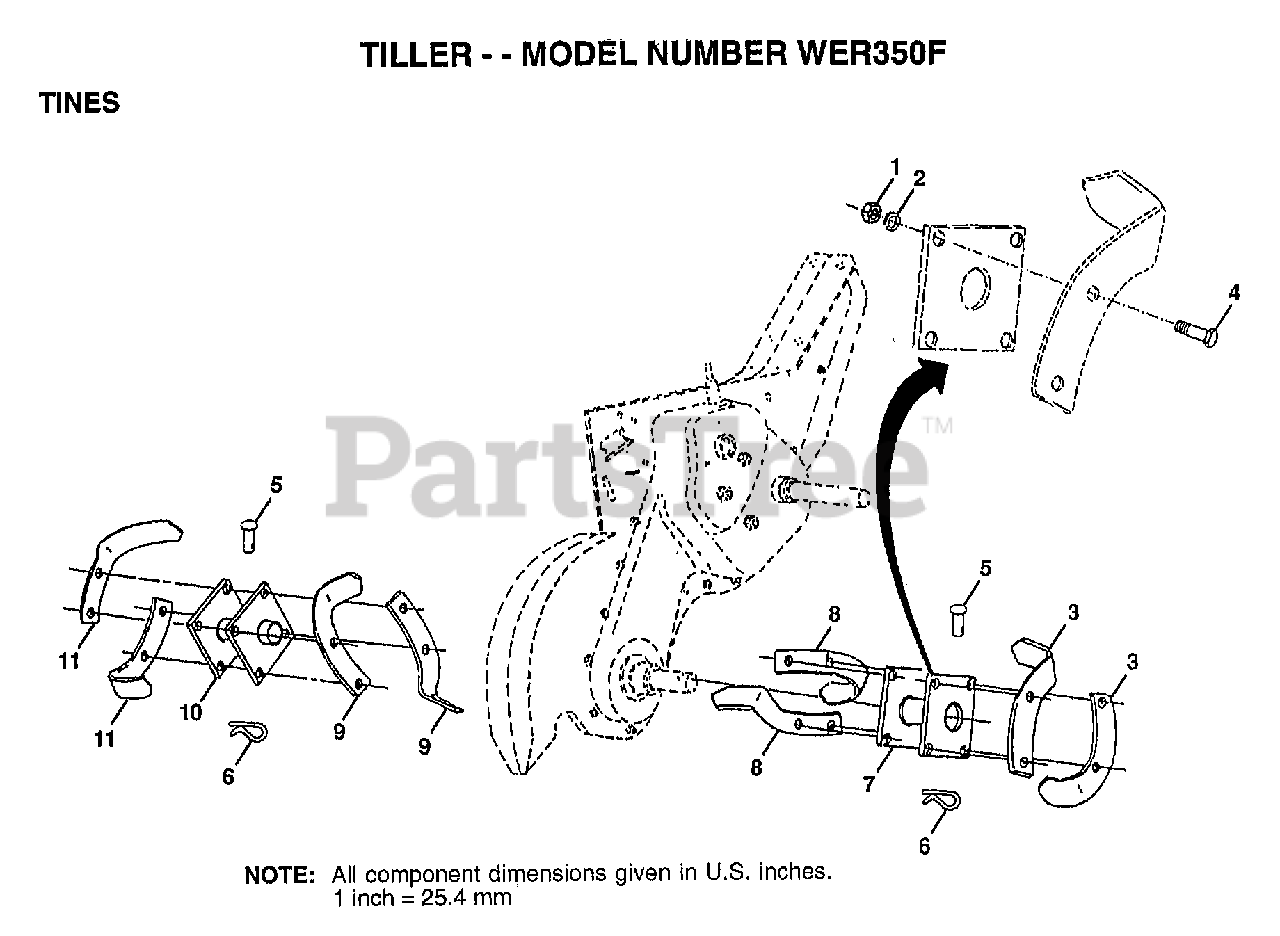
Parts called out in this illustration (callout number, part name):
2	LOCKWASHER
4	BOLT
5	PIN.CLEVIS.SHEAR
6	RETAINER.SPRING
7	ASM HUB&PLATE RH
8	"TINE.RH.12"""
9	"TINE.LH.12"""
10	ASM HUB&PLATE LH
